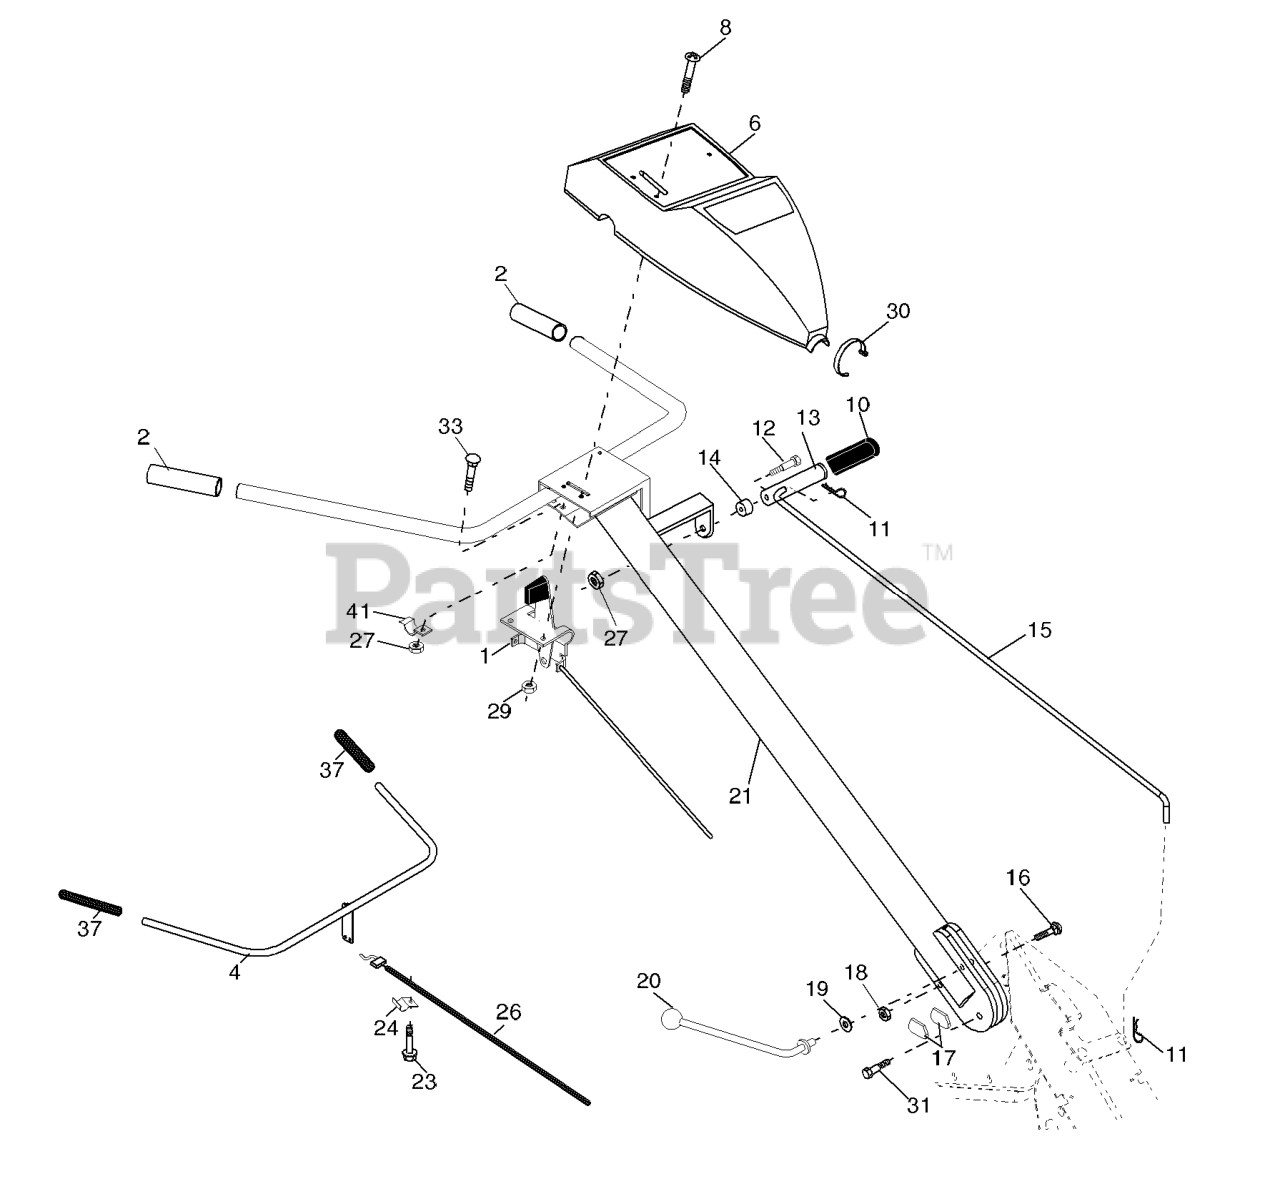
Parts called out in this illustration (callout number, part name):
1	THROTTLE.CONTROL.CRT.TILLER
2	GRIP.HANDLE.BLACK
4	CONTROL BAR ASSY
6	RP CONTROL PANEL
8	SCREW.PNHD.10-24
10	GRIP T
11	RETAINER M
12	SHOULDER BOLT ST
13	HANDLE.SHIFT.TILLER
14	GROMMET.RUBBER.CRT.TILLER
15	SHIFT ROD CRT
16	BOLT D
17	LOCK.HANDLE.CRT
19	WASHER CRT
20	LEVER.LOCK.CRT
21	REPL BY 532 1805-17
23	TAPPING SCREW
24	CONDUIT.CLIP.PLATED
26	CABLE.CLUTCH
27	NUT T
29	NUT **
30	TIE CABLE CRT
31	BOLT.PIVOT
33	BOLT
37	GRIP BAR CRT(1)
41	CLAMP.BAR.CRT.BLACK
